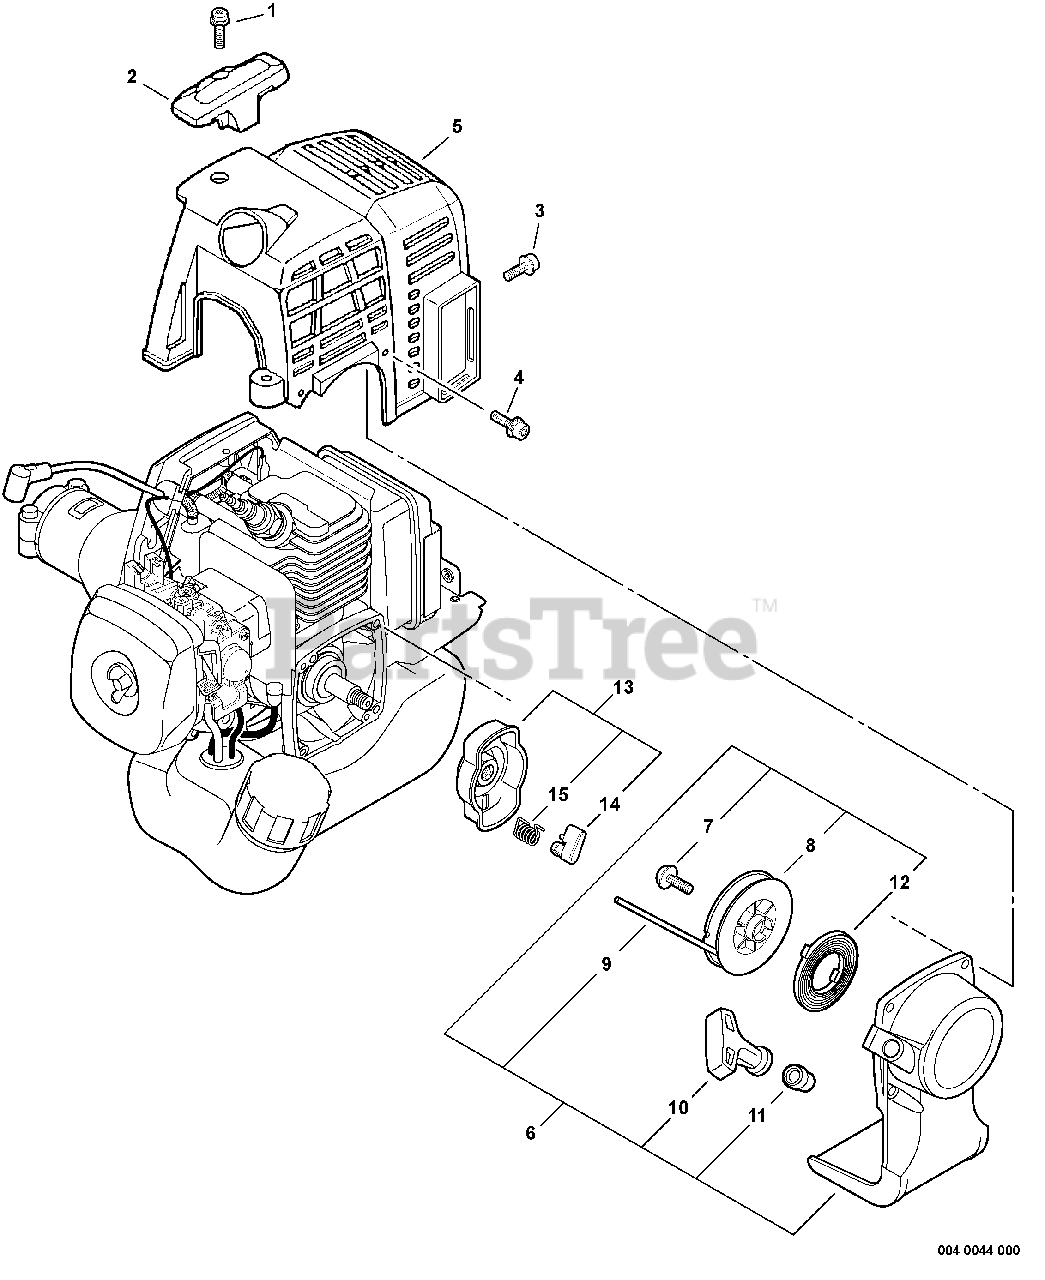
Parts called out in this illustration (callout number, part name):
1	SCREW 5×16
2	GUARD, TOP
3	BOLT 4×8
4	BOLT 4×16
5	COVER, ENGINE
6	STARTER ASSY
7	SCREW
8	REEL, ROPE
9	ROPE, STARTER 3.0×1000
10	GRIP, STARTER
11	GUIDE, ROPE
12	SPRING, RECOIL
13	PAWL ASSY, STARTER
14	PAWL, STARTER - BLACK
15	SPRING, RETURN
